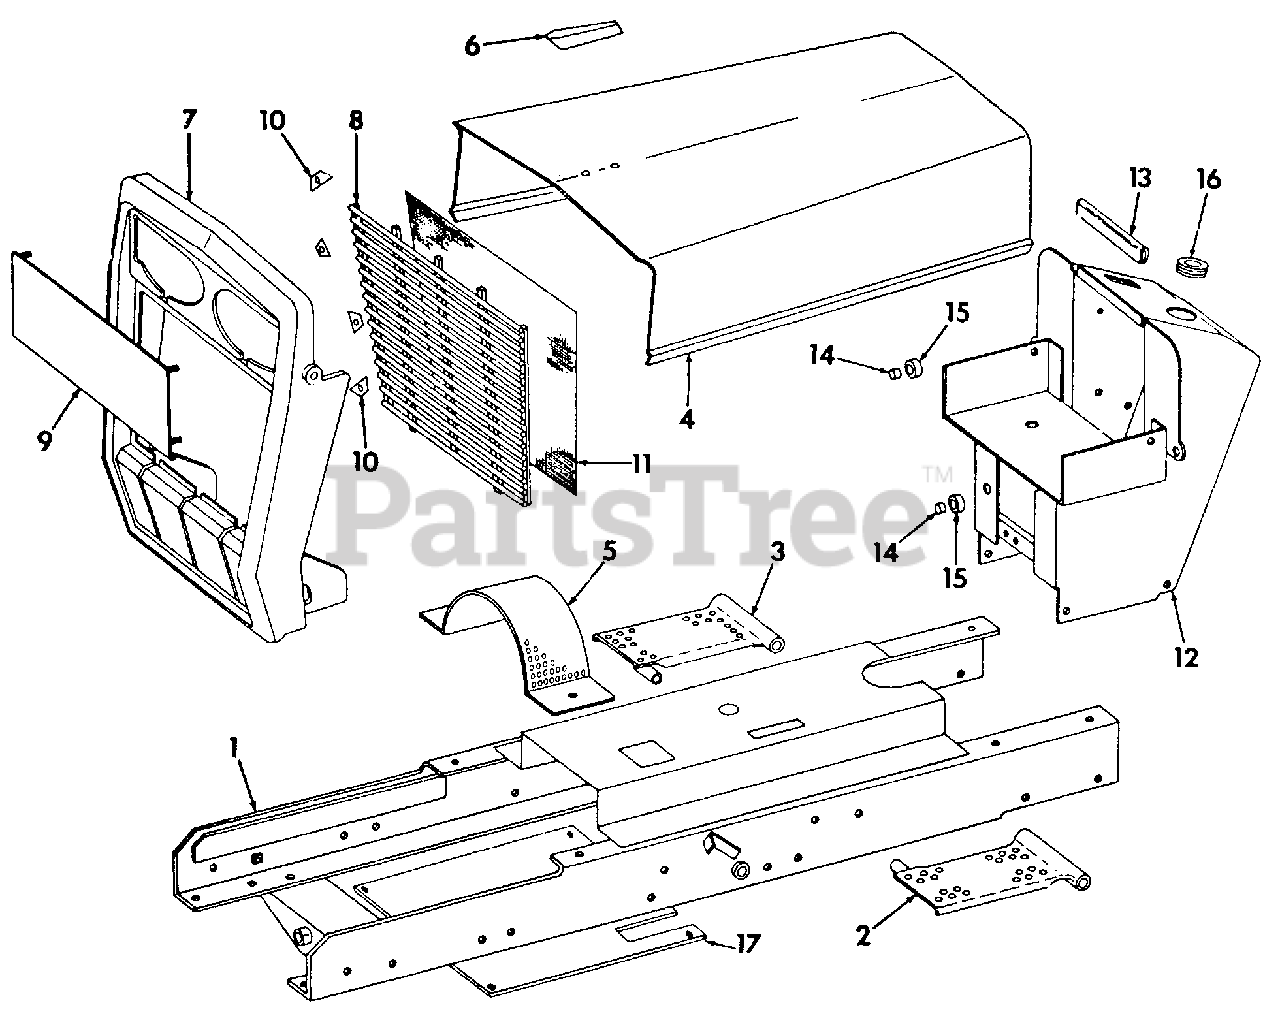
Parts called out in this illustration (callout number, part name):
1	Frame Assy
2	Support Assy, Foot LH
3	Support Assy, Foot RH
4	Hood Assy
5	Shield, Clutch
6	Product Graphic, Hood Ornament
7	Housing, Grille
8	Grille
9	Strip Assy, Grille Panel
10	Strip, Grille Panel Clamp
11	Screen, Grille
12	Pedestal Assy
13	Bumper, Hood
14	Spacer, Hood Roller Lock
15	Roller, Hood Lock
16	Grommet, Instrument Panel
17	Sheet, Bottom Clutch Shield
